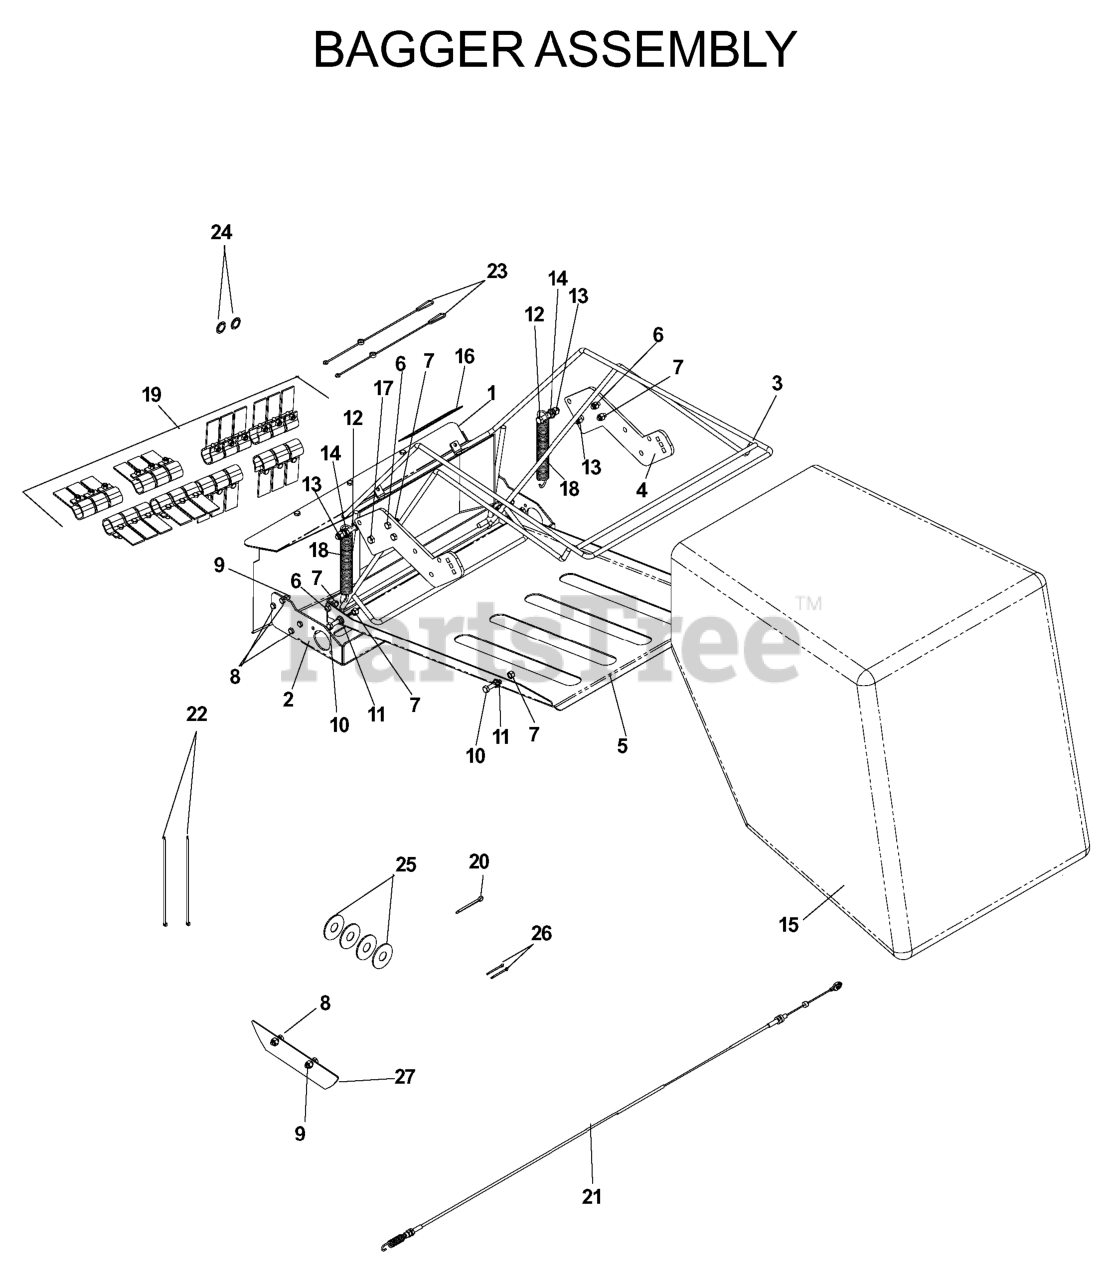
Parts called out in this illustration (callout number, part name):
1	CHUTE
2	BAGGER TRAY
3	BAG FRAME, BLACK
4	EXTENDER GREY
5	SAFETY DOOR ORANGE
6	HCS 5/16C X 1
7	NUT 5/16 NYLOC
8	HCS 1/4C X 3/4 HCS
9	NUT.1/4-20.HEX.NYLOC.ZD
10	HCS 5/16C X 1 3/4
11	NUT 5/16C WHIZ
12	HCS 3/8C X 2
13	NUT 3/8-16 NYLOC
14	NUT 3/8C WHIZ
15	CATCHER BAG
16	DECAL, WARNING
17	HCS 3/8-16X1.GRD.5.ZD
18	SPRING BAGGER
19	KIT, FLAPS W/FASTENERS
20	COTTER PIN
21	CABLE 46.5" POWER RAKE
22	TIE, PLASTIC
24	RETAINING RING
25	WASHER
25	SIDESHIELD
26	COTTER PIN 3/32 X 3/4
539107244	DECAL, HANDLE PIN
